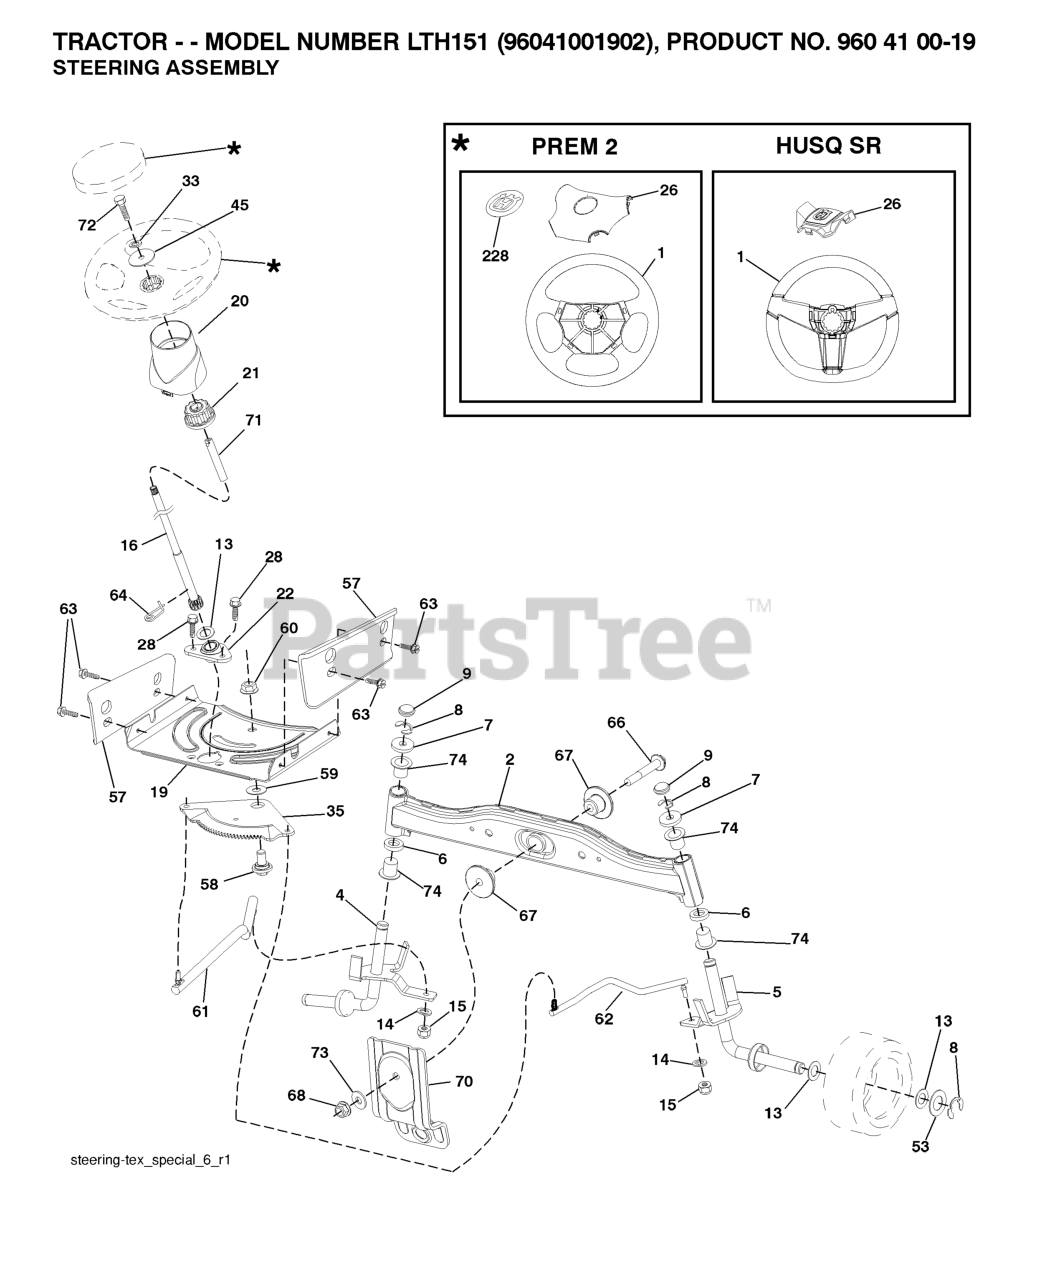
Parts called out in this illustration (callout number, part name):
1	RP WHEEL.STEER.HUSQ.PREM.OVMLD
2	AXLE.HALF.ASM.WELDED
4	SPINDLE.WELDED.LH.15"TEX
5	SPINDLE.WELDED.RH.15"T
6	THRUST WASHER
9	CAP.SPINDLE.BLACK
14	WASHER, LOCK 3/8
15	NUT CROWNLOCK 3/8-24
16	SHAFT STEERING
19	PLATE.STEER.DDL.NLT/NG
20	BOOT, STEERING
21	ADAPTER, WHEEL STNG..
22	BUSHING.ASM.STEERING.A
26	RP INSERT.CAP.WHL.STRG.HUSQ.
28	SCREW, 3/8-16X3/4
33	WASHER.LOCK.HVY.HLCL.SPR.5/16
35	GEAR.SECTOR.PLATE.DDL.
45	WASHER.11/32
53	WASHER.HARDENED
57	BRACKET.UPSTOP.TEX
58	BOLT.SHOULDER.SECTOR.P
59	WASHER.THURST.SECTOR.S
60	NUT FLANGE LOCK 5/8-11
61	DRAGLINK.LH.BALLSTUD.D
62	DRAGLINK.RH.BALLSTUD.D
63	SCREW
64	RETAINER.CLIP.SPRING.S
66	BOLT HEX FGHD 7/16-14 X 3 SERR
67	BUSHING.PM.FRONT AXLE
68	NUT.LOCK.FLANGE.7/16
70	BRKT.DECK.SUSPENSION.F
71	SHAFT EXTENSION STEERING
72	BOLT YT
73	WASHER.1.5X.505X.118
74	BRNG T
228	DECAL.WHEEL.STRG.LGN.H
